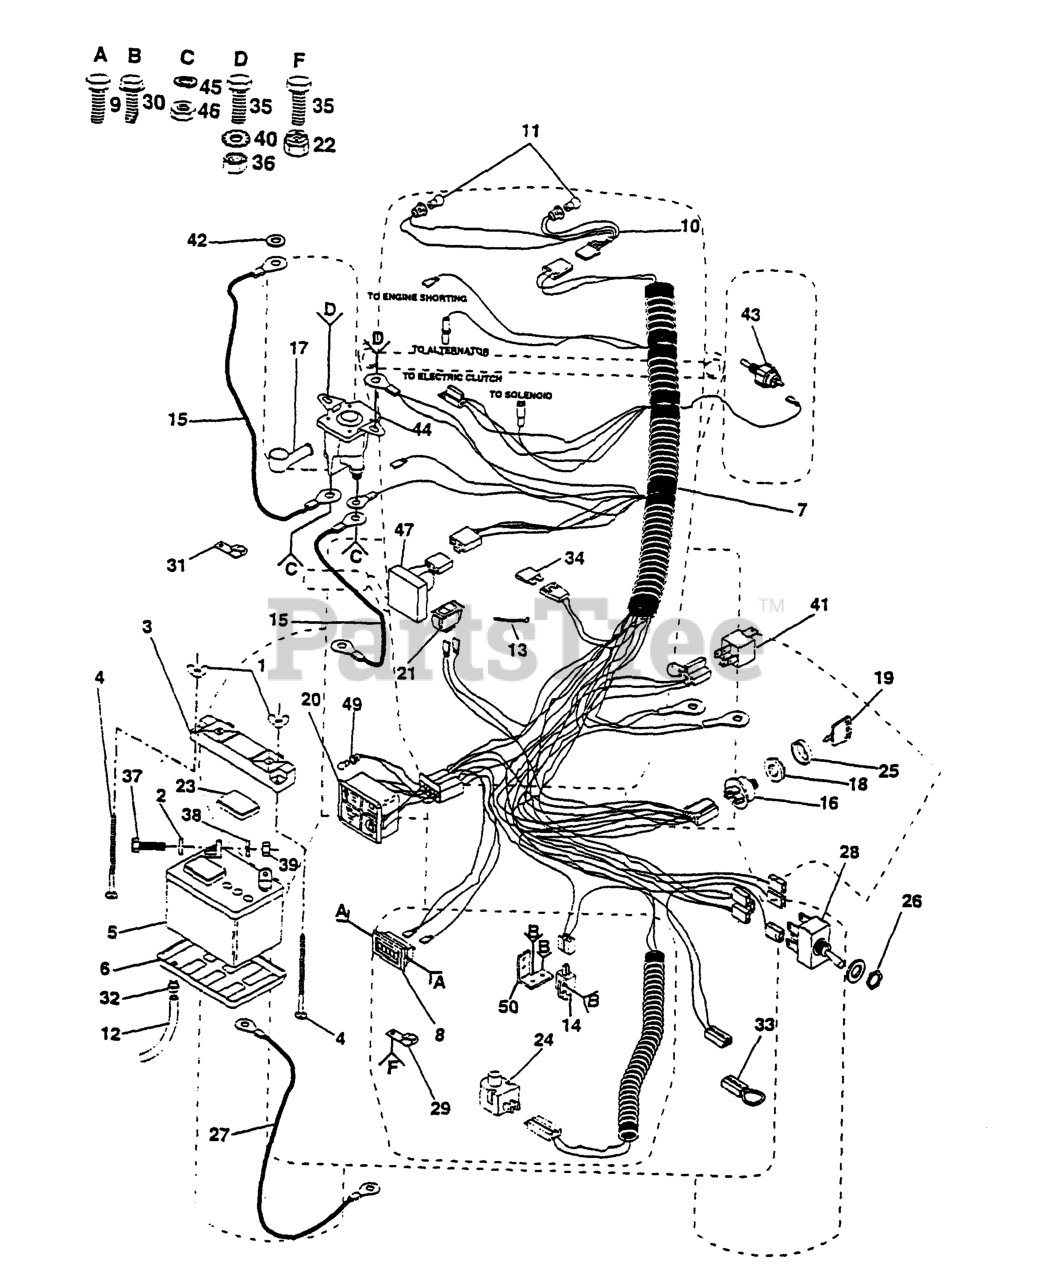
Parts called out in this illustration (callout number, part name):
1	WING NUT
2	WASHER
3	TERMINAL GRD YTV
5	BATTERY
6	BATTERY TRAY T
7	HARNESS IGNITION
8	HOUR METER T
9	Screw #10-24 x 1/2
10	HARNESS, LIGHT SOCKET
11	BULB-LIGHT T
12	PLASTIC TUBE
13	TIE GUIDE
14	SWITCH-INTER. GT
15	CABLE-BATTERY YTV
16	SWITCH YTV
17	TERMINAL COVER
18	NUT IGNITION
19	KEY.MOLDED.GENERIC
20	LIGHT PACKAGE
22	NUT.CROWNLOCK.1/4
23	CAP BATTERY NLA
24	RP.SWITCH.PLUNGER.NC.GRAY
25	COVER KEY IGNITIO
26	HEX NUT T
27	CABLE T
28	SWITCH,PTO
29	PANEL,SIDE LH
31	CLIP T
32	HOSE CLAMP T
33	LOOP-WIRE YTV
35	BOLT
36	NUT
37	BOLT.HEX.1/4.X.3/4.DICHROMATE
38	LOCKWASHER
39	NUT
40	Washer, Lock, External Tooth 1/4
41	RELAY.ASSY.T
42	Washer, Lock, Internal Tooth 1/4
43	SWITCH OIL SENSOR
44	SOLENOID
45	LOCKWASHER
46	NUT
47	SENSOR LOW VOLTAGE
48	WASHER
49	BULB LIGHT T
50	BRACKET LT
